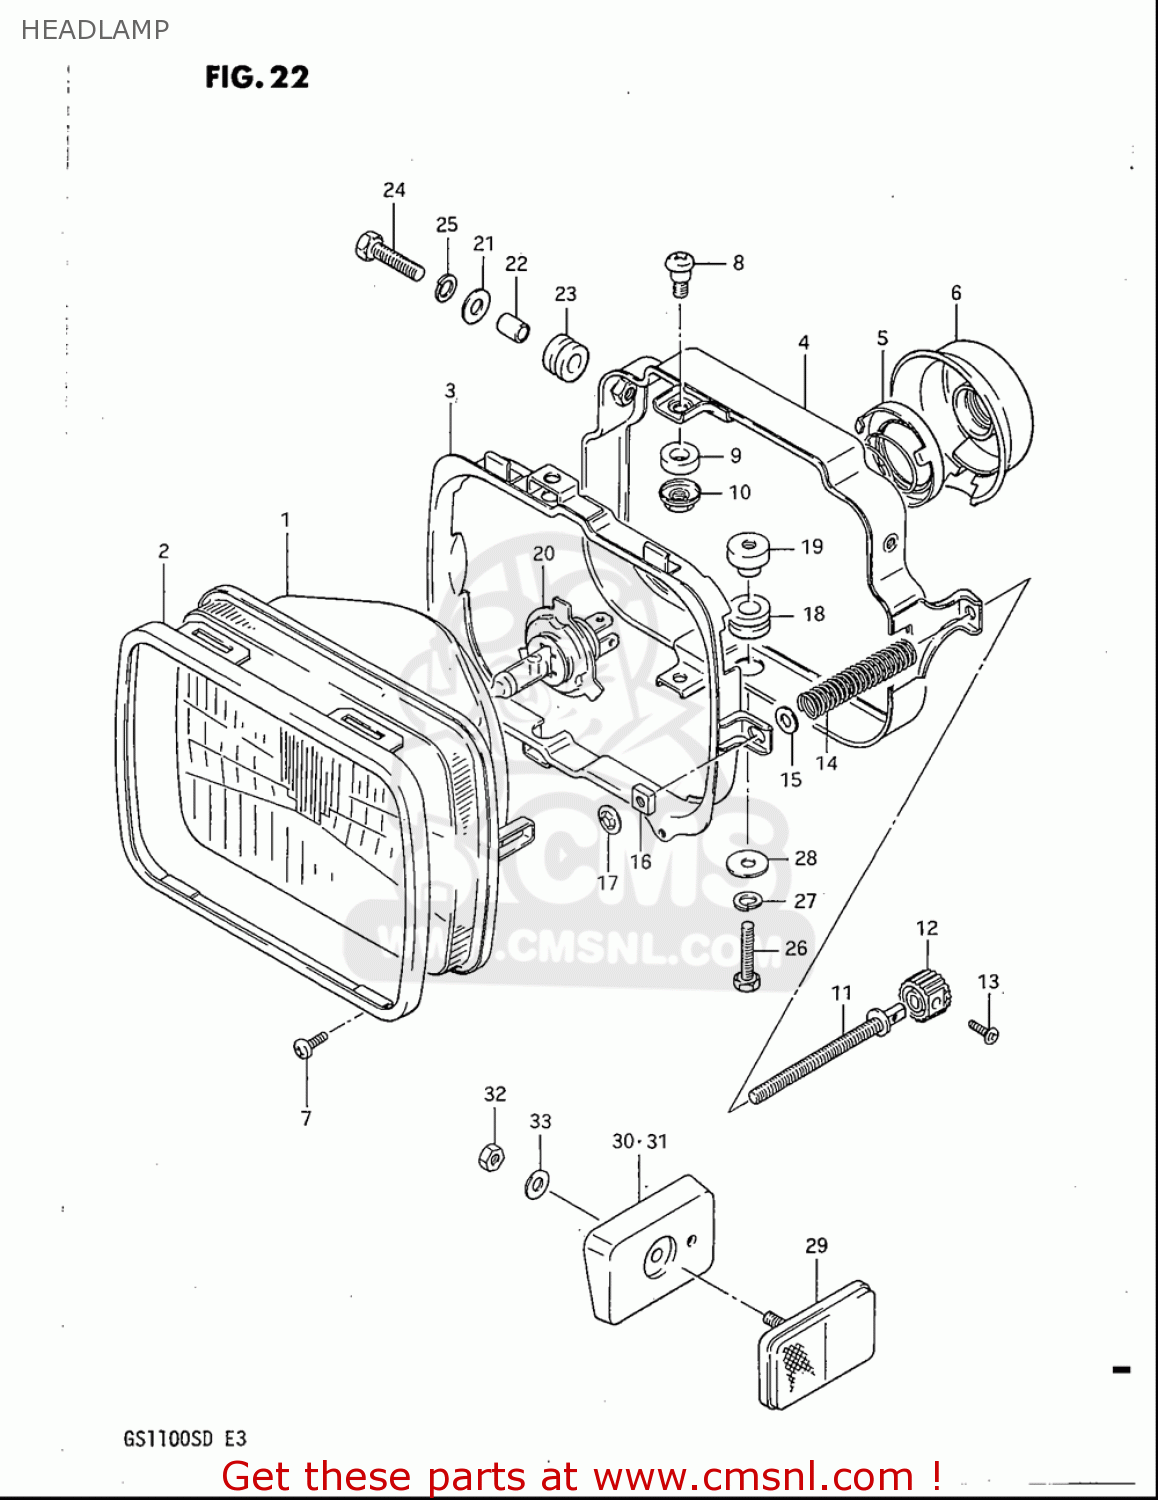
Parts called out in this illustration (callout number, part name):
1	LAMP UNIT
2	RETAINER
4	HOUSING
5	HOLDER
6	COVER,SOCKET
7	SCREW
8	SCREW,HEAD LAMP RIM
9	SPACER
10	NUT
11	SCREW,ADJUSTING
12	SCREW
13	SCREW
15	WASHER(6.5X12X1.2)
17	NUT
18	CUSHION
19	NUT
20	BULB(12V60/55W,H4)
21	WASHER(6.5X18X1.6)
22	SPACER(6.1X8X9.5)
23	CUSHION
24	BOLT
25	WASHER,LOCK
27	WASHER,LOCK
28	WASHER
29	REFLECTOR,REFLEX
30	SPACER,FRONT REFLEX REFLECTOR
32	NUT
33	WASHER
